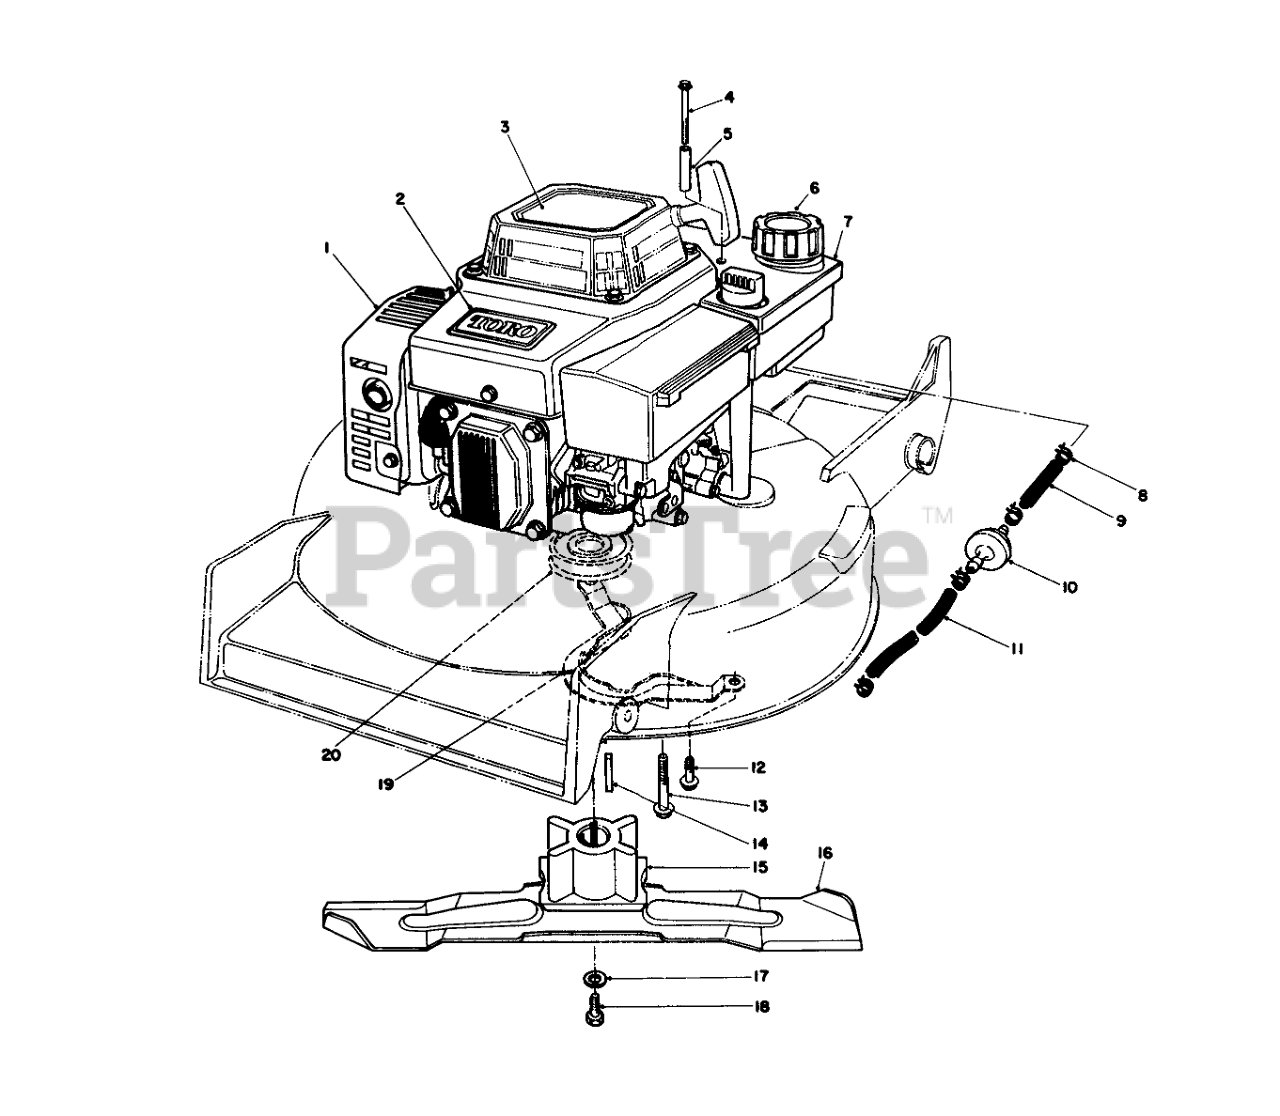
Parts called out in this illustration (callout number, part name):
1	Engine
2	TORO LOGO PLT
3	DECAL-HV INT'L
4	THRD FORMING SCREW
5	TUBULAR SPACER
6	GAS CAP ASM
7	TANK ASM
8	CLAMP-FUEL LINE
9	LINE-GAS
10	FILTER-FUEL
11	HOSE-FUEL
12	Screw
13	SCREW-HWHTF
14	KEY-SQUARE
15	Retainer Blade
16	BLADE-21in
17	WASHER-LOCK
18	SCREW-BLADE
19	BELT GUIDE
20	PULLEY-DRIVER
